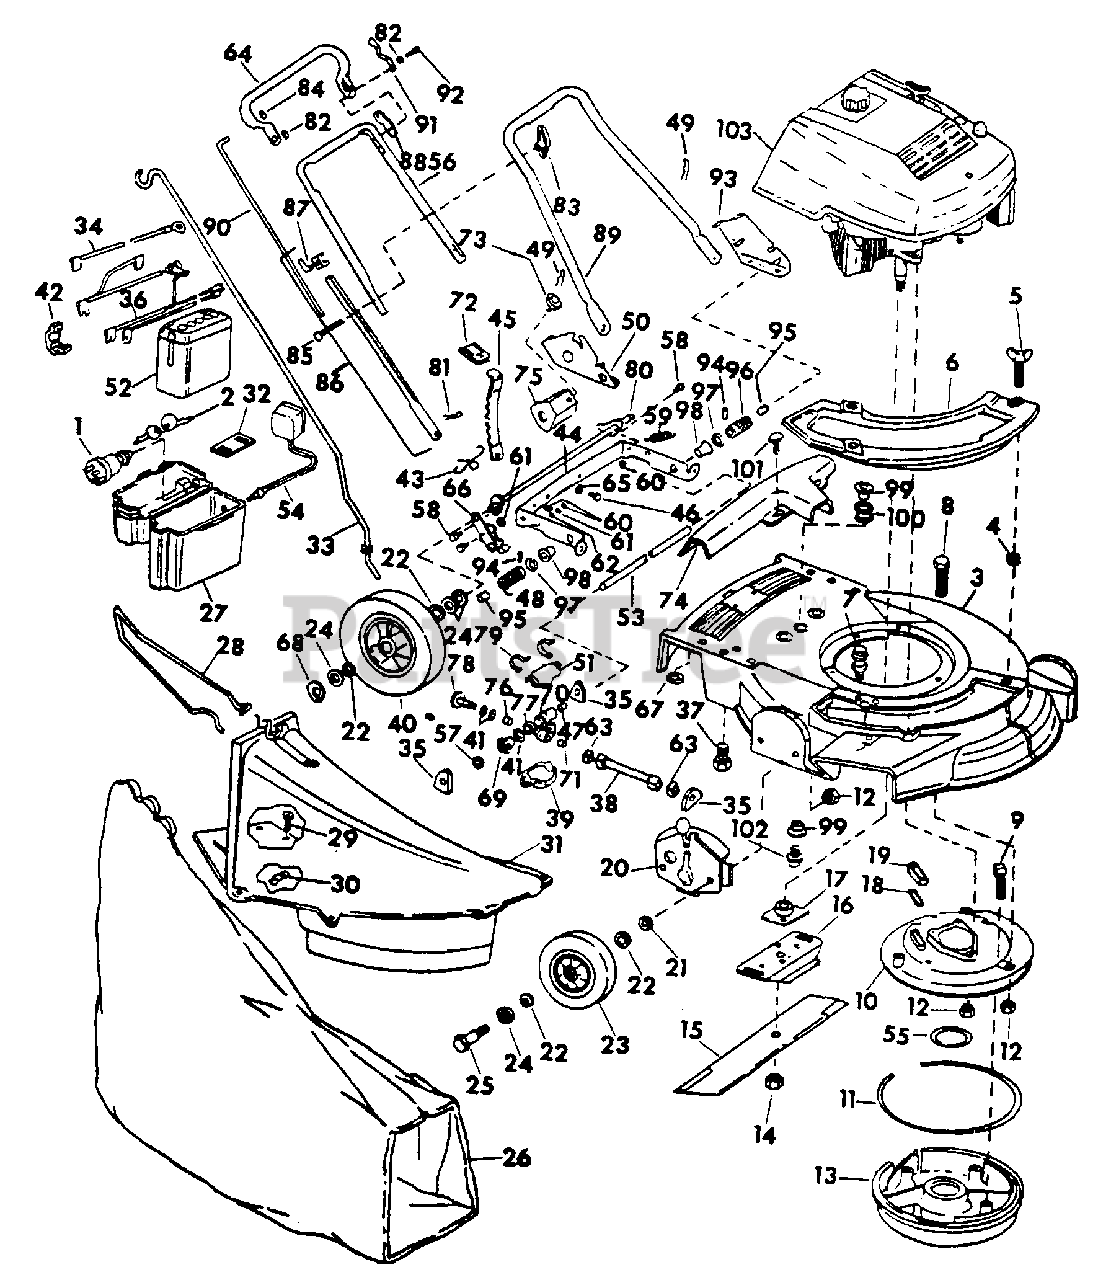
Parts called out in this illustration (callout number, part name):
3	HOUSING ASSY, 21 IN.
4	NUT, GROMMET
5	SCREW, WING
6	COVER, CHUTE OPENING
7	SCREW, SHOULDER
8	SCREW, MUFFLER PLT TO HSG
9	SCREW, MUFFLER TO PLATE
10	PLATE, MUFFLER
11	GASKET, MUFFLER OUTSIDE
13	COVER, MUFFLER
15	BLADE, 21 IN.
16	STIFFENER, BLADE
17	COLLAR & PLATE
18	GASKET, EXHAUST
19	SLEEVE, EXHAUST GASKET
20	ADJUSTMENT, HEIGHT -2-
22	WASHER, FELT
23	WHEEL AND TIRE - (6 IN. FRONT)
24	WASHER, WHEEL BOLT HD
25	BOLT, WHEEL FRT SHOULDER
27	BOX, BATTERY
28	GUARD, WHEEL
31	CHUTE ASSY
32	STRAP, BATTERY BOX MTG
33	ROD, GRASS BAG
39	COVER, GEAR BOTTOM
40	WHEEL & TIRE. 8 IN. REAR
41	WASHER, THRUST
42	POD. INSULATION
43	SPRING, HEIGHT ADJ
45	LEVER, HGT ADJ
47	BEARING, NEEDLE
48	ROLLER, DRIVE RH
50	BRACKET, HANDLE RH
51	COVER, GEAR TOP
52	BATTERY, DRY CHARGED
54	CHARGER, TRICKLE
55	GASKET, MUFFLER INSIDE
56	HANDLE, CENTER
57	WASHER, FELT
58	BOLT, SHOULDER
64	HANDLE & GRIP
67	WASHER, BATTERY MOUNTING BRACKET
69	GEAR, DRIVEN
70	BRACKET & BRG ASSY
71	BEARING, NEEDLE
74	COVER, DRIVE
75	GUARD, ROLLER
76	BEARING, NEEDLE
77	BEARING, NEEDLE
78	GEAR, DRIVE
79	CLAMP, COVER
84	NUT, PUSH
86	LEVER ASSY, CONTROL
89	HANDLE, BOTTOM
90	ROD, CONTROL
91	KNOB & SPRING, LOCKOUT
92	BOLT, SHOULDER
93	BRACKET, HANDLE LH
94	PIN, ROLLER TO SHAFT
95	PLUG, ROLLER GREASE
96	ROLLER, DRIVE LH
97	WASHER
98	SLEEVE & BEARING
99	SPACER, FLANGED
101	SCREW, HEX-HD
103	ENGINE, IH
